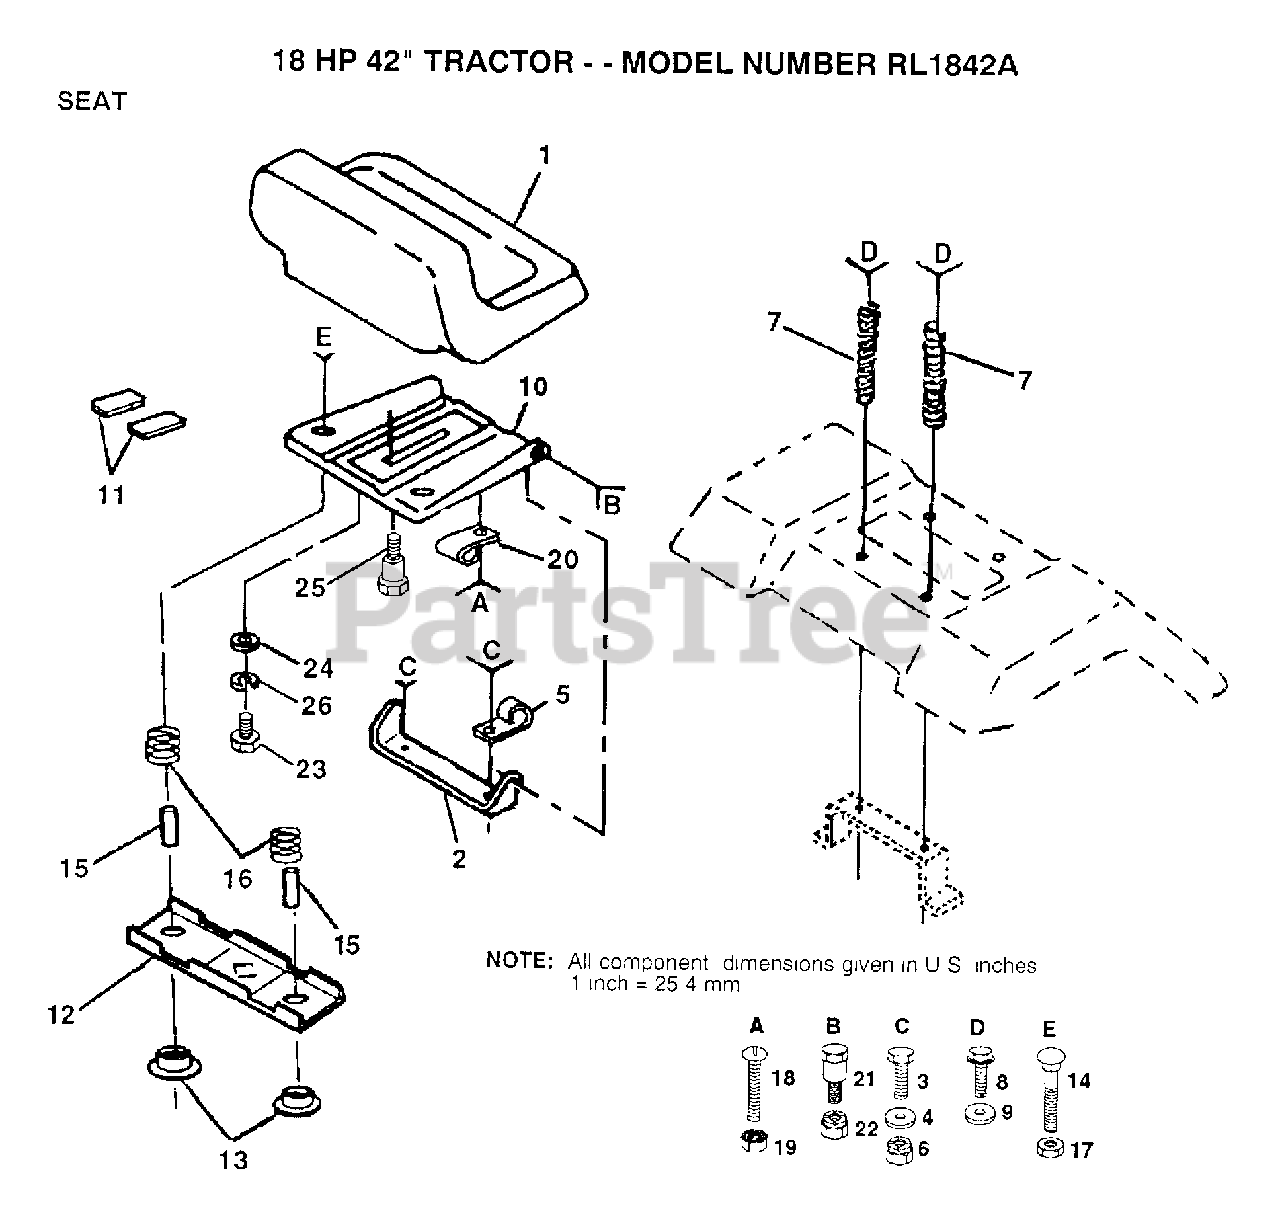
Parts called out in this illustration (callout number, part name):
4	WASHER PM
5	CLIP T
7	SPRING COMPRESSIO
8	SCREW GTV
9	WASHER
11	STRIP FORM
12	BRKT SWITCH
13	BUSHING
15	SPACER SPLIT
16	SPRING COMPRESSED
19	"NUT,KEPS"
23	BOLT
24	WASHER
25	"BOLT,SHOULDER"
26	LOCKWASHER
